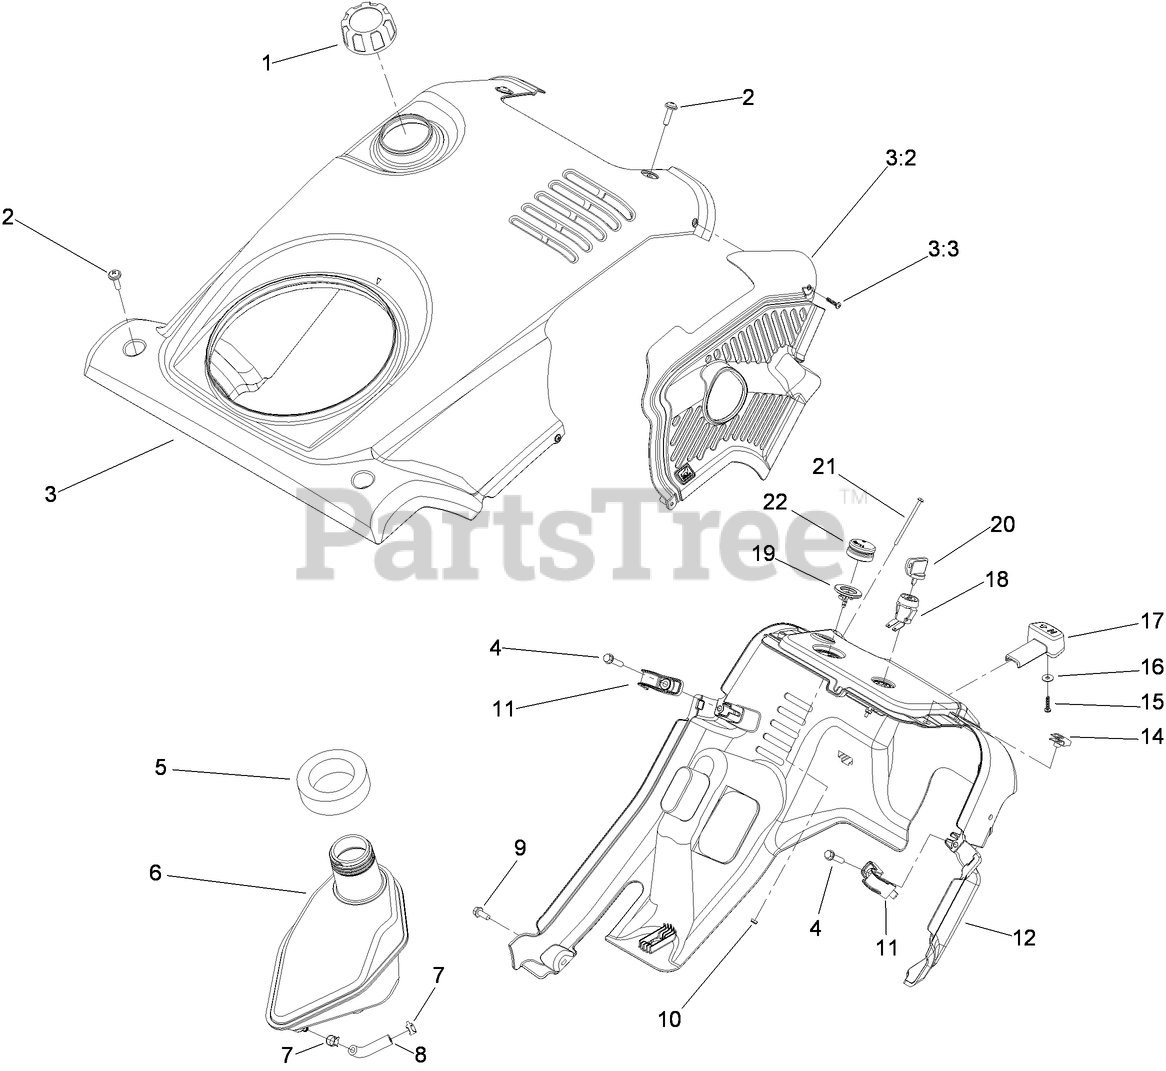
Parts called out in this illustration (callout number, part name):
1	4-CYCLE GAS CAP ASM
2	SCREW-PPH
3	SHROUD ASM
3:2	BAFFLE-EXHAUST
3:3	SCREW-PPH
4	SCREW-PLASTITE
5	SEAL-TANK
6	TANK-GAS
7	CLAMP-HOSE
8	HOSE-FUEL
9	SCREW-HWH
10	NUT-HEX
11	CLIP-SHROUD
12	SHROUD-LOWER
15	SCREW-PPH
16	WASHER-PLAIN
17	KNOB-CHOKE
18	SWITCH
19	BODY-PRIMER
20	KEY-IGNITION
21	SCREW-HWH
22	BULB-PRIMER
